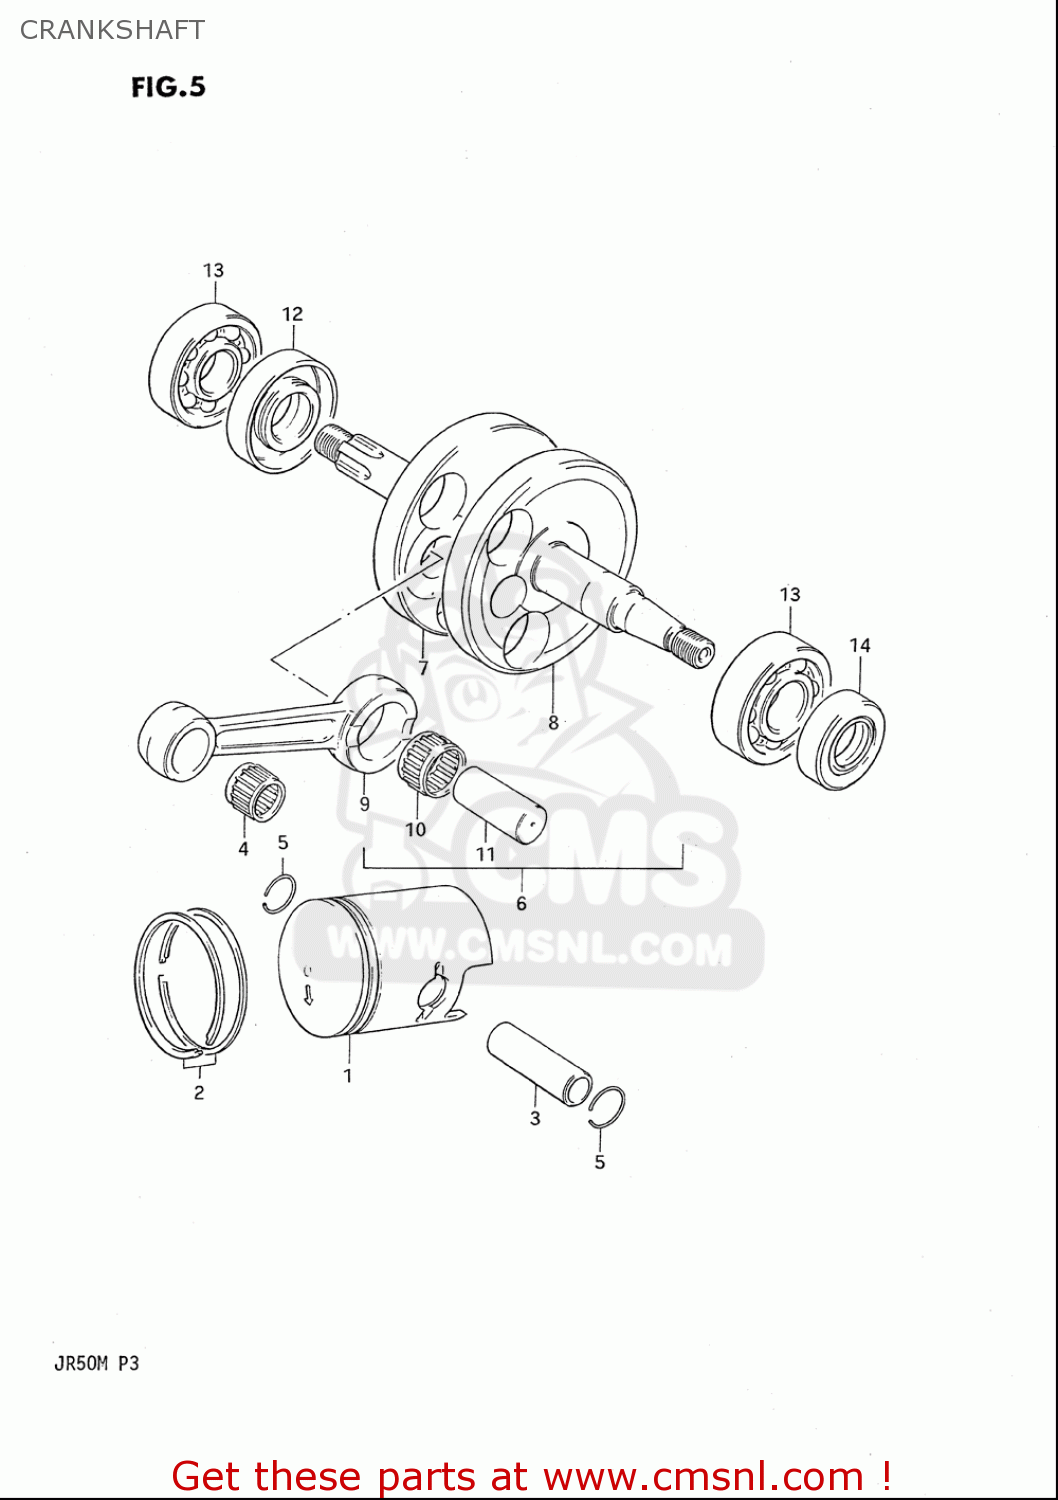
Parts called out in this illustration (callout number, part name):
1	PISTON (41.00MM)
2	RING SET,PISTON
3	PIN,PISTON
4	BEARING(12X16X16)
5	RING,SNAP
6	CRANKSHAFT ASSY
7	CRANKSHAFT,R
8	CRANKSHAFT,L
9	ROD,CONNECTING
10	BEARING(15X21X9.8)
11	PIN,CRANK
12	SEAL,OIL(22X40X8)
13	BEARING(17X40X12)
14	SEAL,OIL(17X29X7)
